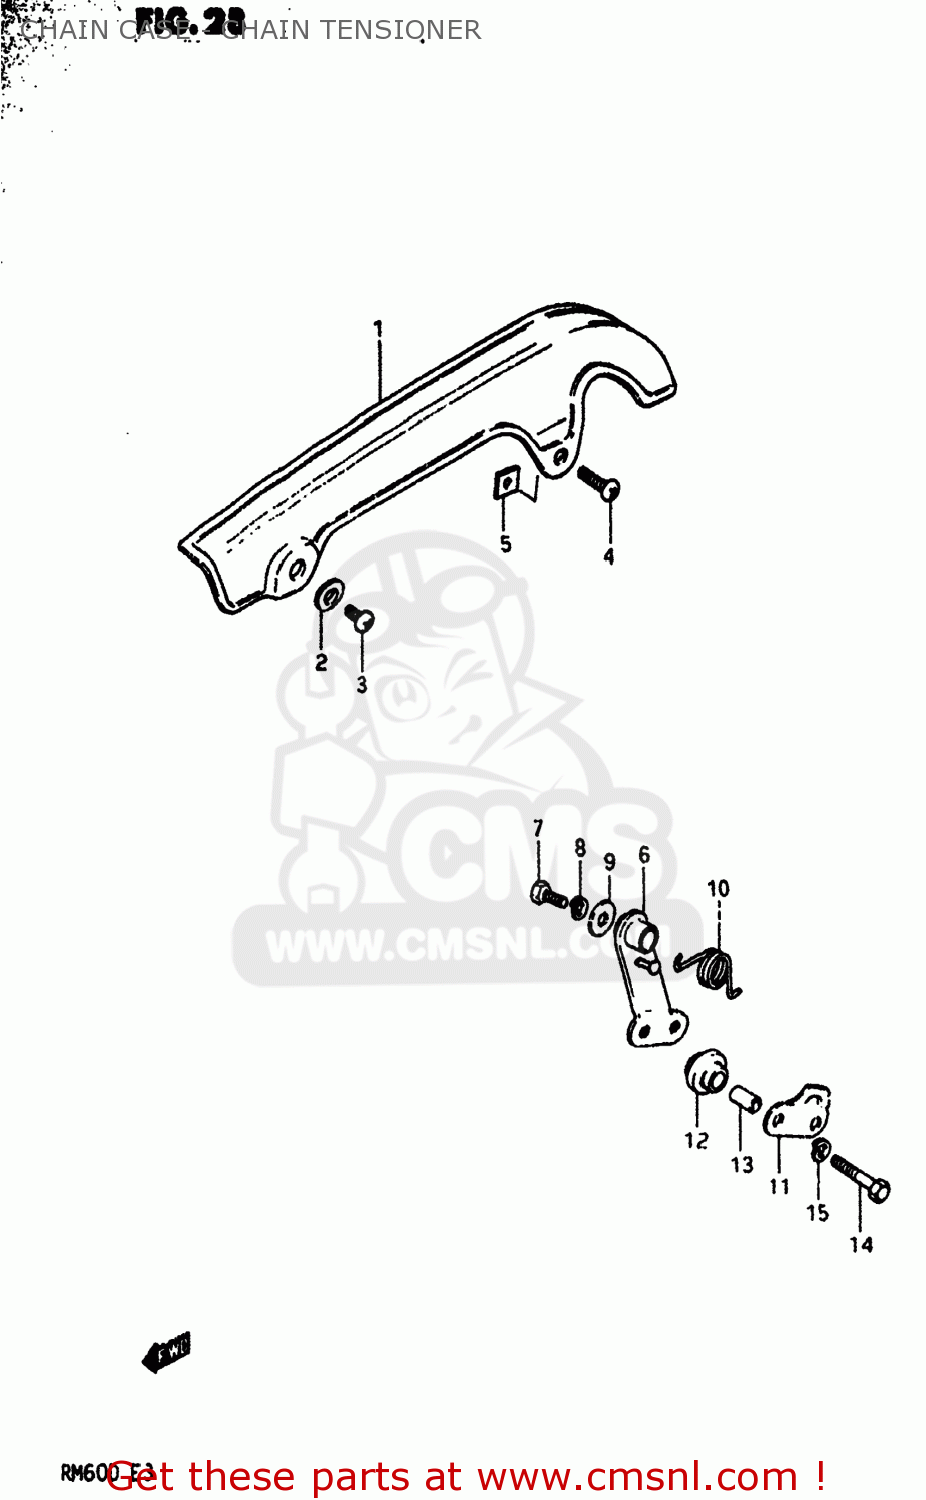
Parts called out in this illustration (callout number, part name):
1	CASE,CHAIN
2	WASHER
3	SCREW
4	SCREW 6X12
5	NUT,CHAIN CASE RR
6	TENSIONER,CHAIN
7	BOLT
8	LOCK WASHER
9	WASHER
10	SPRING
11	PLATE,CHAIN TENSIONER
12	RUBBER,CHAIN GUARD
13	SPACER(6.5X10.5X22.5)
14	BOLT
15	LOCK WASHER
